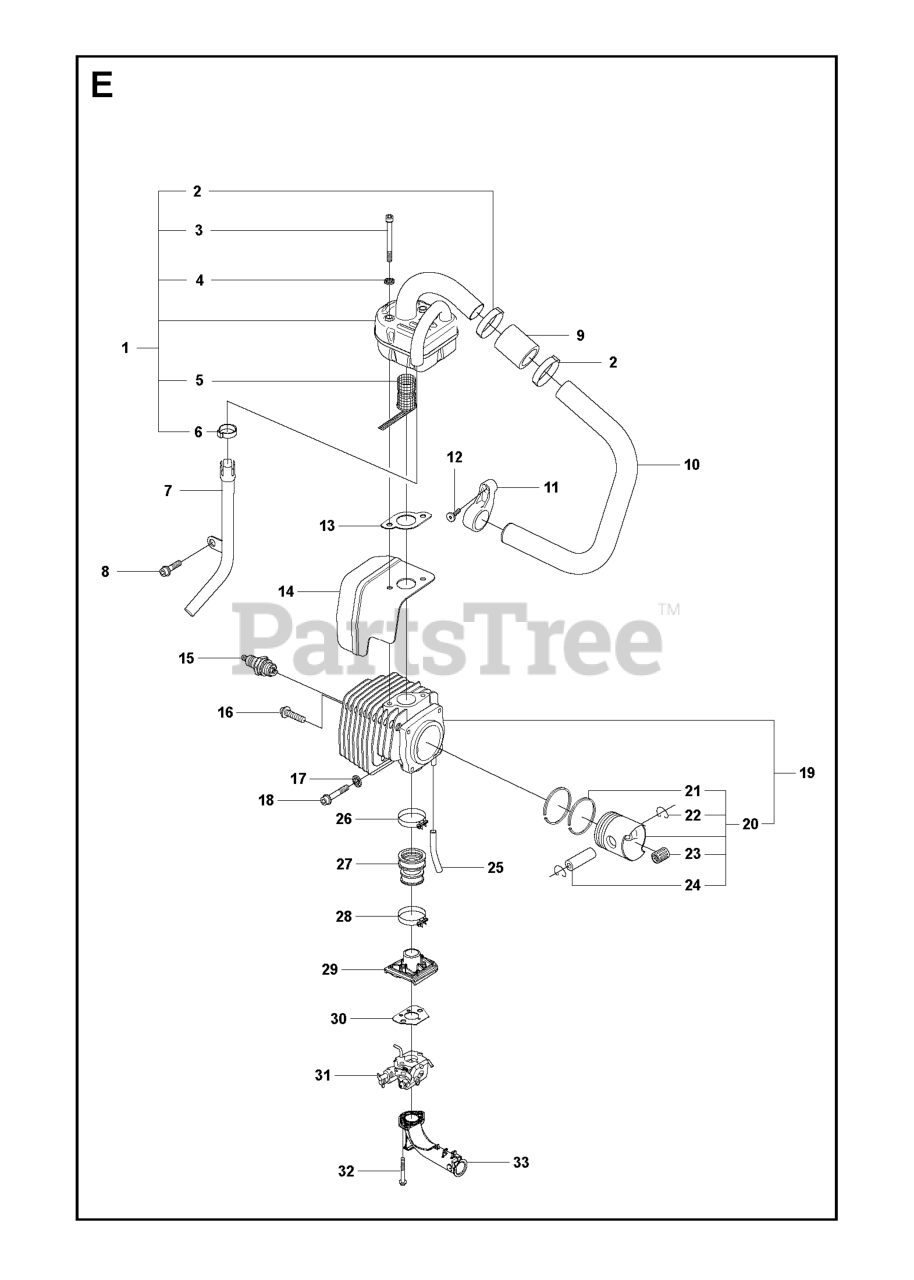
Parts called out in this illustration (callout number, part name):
4	DOUBLE WASHER
5	SPARK ARRESTOR
10	PIPE
12	SCREW M5X14
15	SPARK PLUG RCJ7Y
16	SCREW MC6S 5X25
17	DOUBLE WASHER
20	PISTON CPL 44MM
21	PISTON RING
22	WRIST PIN CLIP
23	BEARING
24	PISTON BOLT
25	FUEL HOSE
26	CLAMP
27	INLET TUBE
28	CLAMP
31	CARBURETOR
33	PIPE
33	INLET BEND 5MM WIRE
